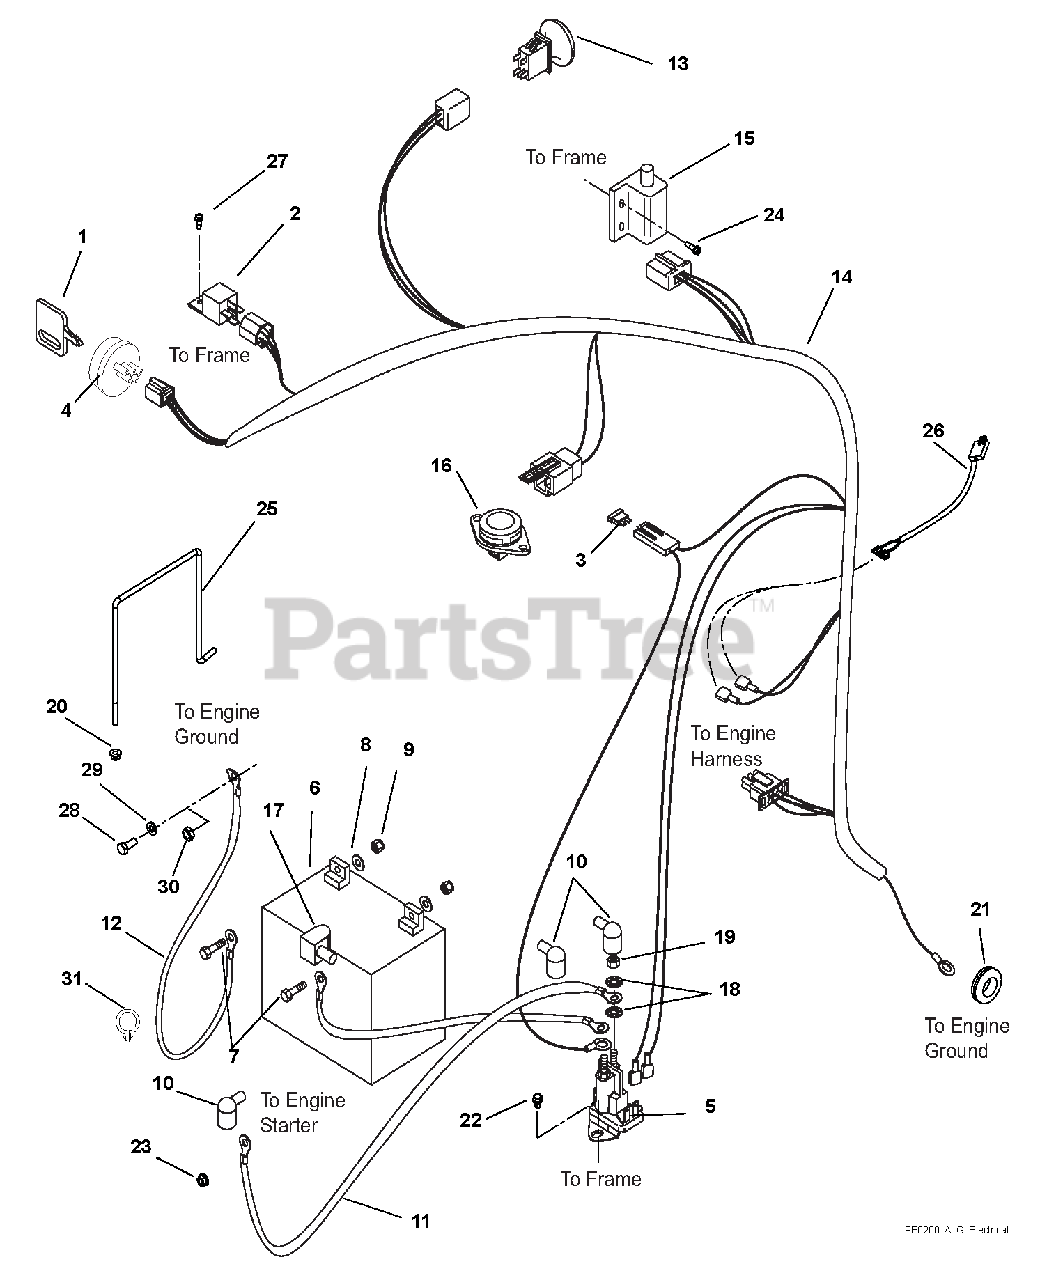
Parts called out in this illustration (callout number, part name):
1	KEY, 03290500 KEYSWITCH
2	RELAY
3	FUSE-25 AMP ATC TYPE
4	KEYSWITCH-IGNITION 3 POS
5	SOLENOID, HP RTV
6	Battery, Sealed Maintenance free U1-250 (Purchase replacement locally)
7	@BLT-HEX .25-20X.75 GR5 YWZC
8	@WSHR-FL-STL.281X.62X.065 YWZC
9	NUT-KEPS .250-20
10	BOOT, EYELET TERMINAL
11	CABLE, POS. BAT. 14.25"
12	CABLE, GROUND 26.00"
13	SWITCH, CLUTCH
14	HARNESS-WIRING, BBZ
15	SWITCH- DOUBLE POLE N.O./N.O.
16	SWITCH- SEAT
17	INSULATOR
18	WSHR-LOCK INT .31 YWZC
19	NUT-JAM .31-24 YWZC
20	@NUT-LK-NYL-FLG .25-20 YWZC
21	GROMMET 1.0ID X 1.38 OD
22	@SCR-TAP .25-20X.37 HWH YWZ TR
23	@NUT-LK-TOP-FLG .25-20 YWZC
24	SCR- 12-14X.75 HX W/HD TEK ZC
25	HOLD DOWN, BATTERY
26	HARNESS, CLUTCH
27	@SCR-TAP 12-24X.50 HWH TR YWZC
28	@BLT-HEX M8-1.25X20 YWZC
29	@WSHR-LK .31X.078 REG YWZC
30	@NUT-LK-CTR-JAM .375-16 YWZC
31	WIRE CLIP
